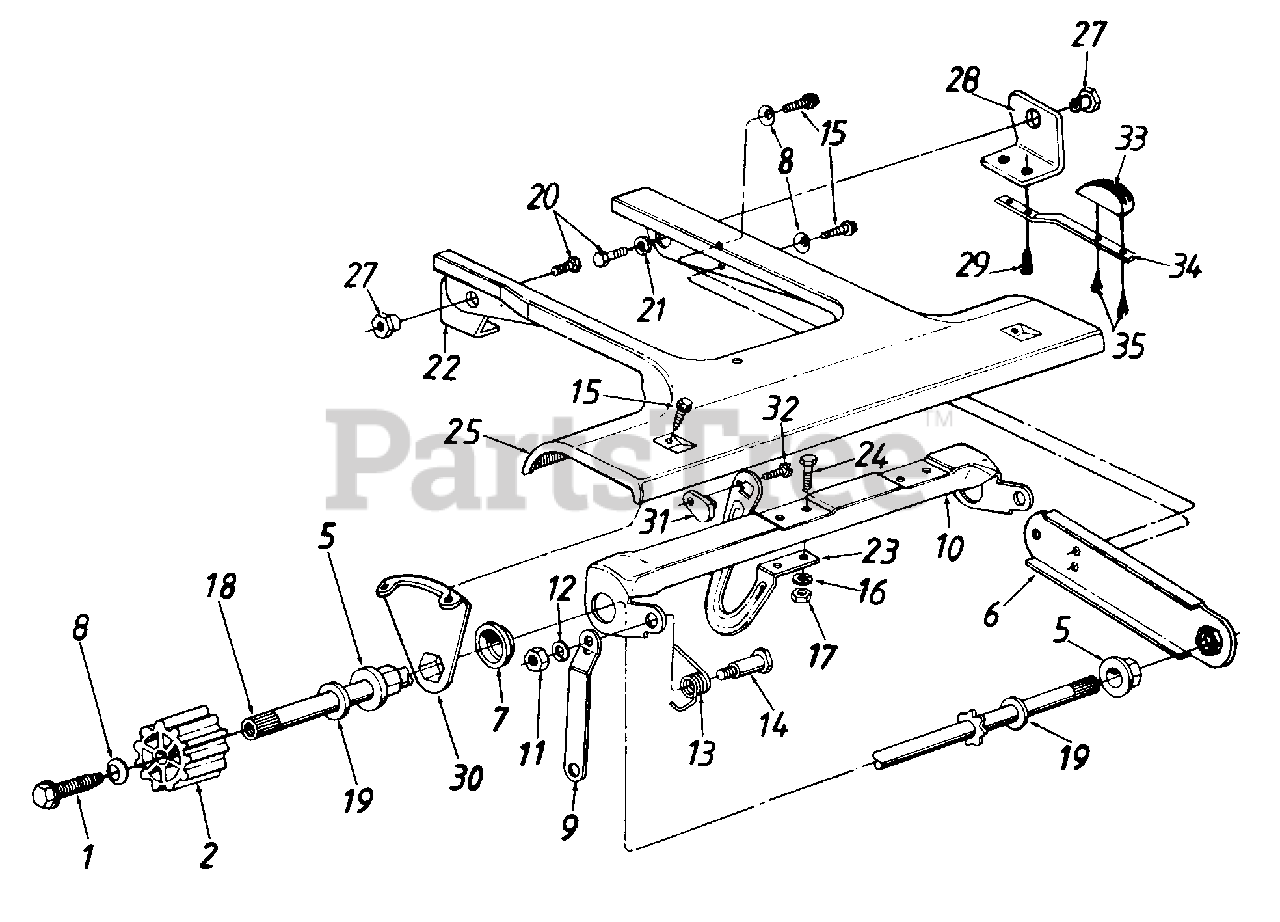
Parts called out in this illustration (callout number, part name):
1	Hex Wash. Hd. Tap Scr. 1/4-20 x .75" Lg.
2	Wheel Drive Pinion
5	Hex Flange Brg. .504" I.D.
8	Bell-Wash. .265" I.D. x .75" O.D.
9	Link 5.06" Lg.
10	Drive Engagement Cam
11	Hex Nut 5/16-18 Thd.
12	L-Wash. 5/16" I.D.
13	Torsion Spring-R.H.
14	Shoulder Bolt .437" Dia.
15	Hex Wash. Hd. AB-Tap Scr. 1/4 x .62" Lg.
16	L-Wash. 1/4" I.D.
17	Hex Nut 1/4-20 Thd.
18	Drive Shaft Ass'y.
19	Fl-Wash. .531" I.D. x .93" O.D.
20	Hex Bolt 3/8-16 x .5" Lg.
21	L-Wash. 3/8" I.D.
32	Hex B-Tap Scr. #10 x .44" Lg.
33	Chain Tensioner
34	Cantilever Spring
35	Hex B-Tap Scr. #10 x .38" Lg.
